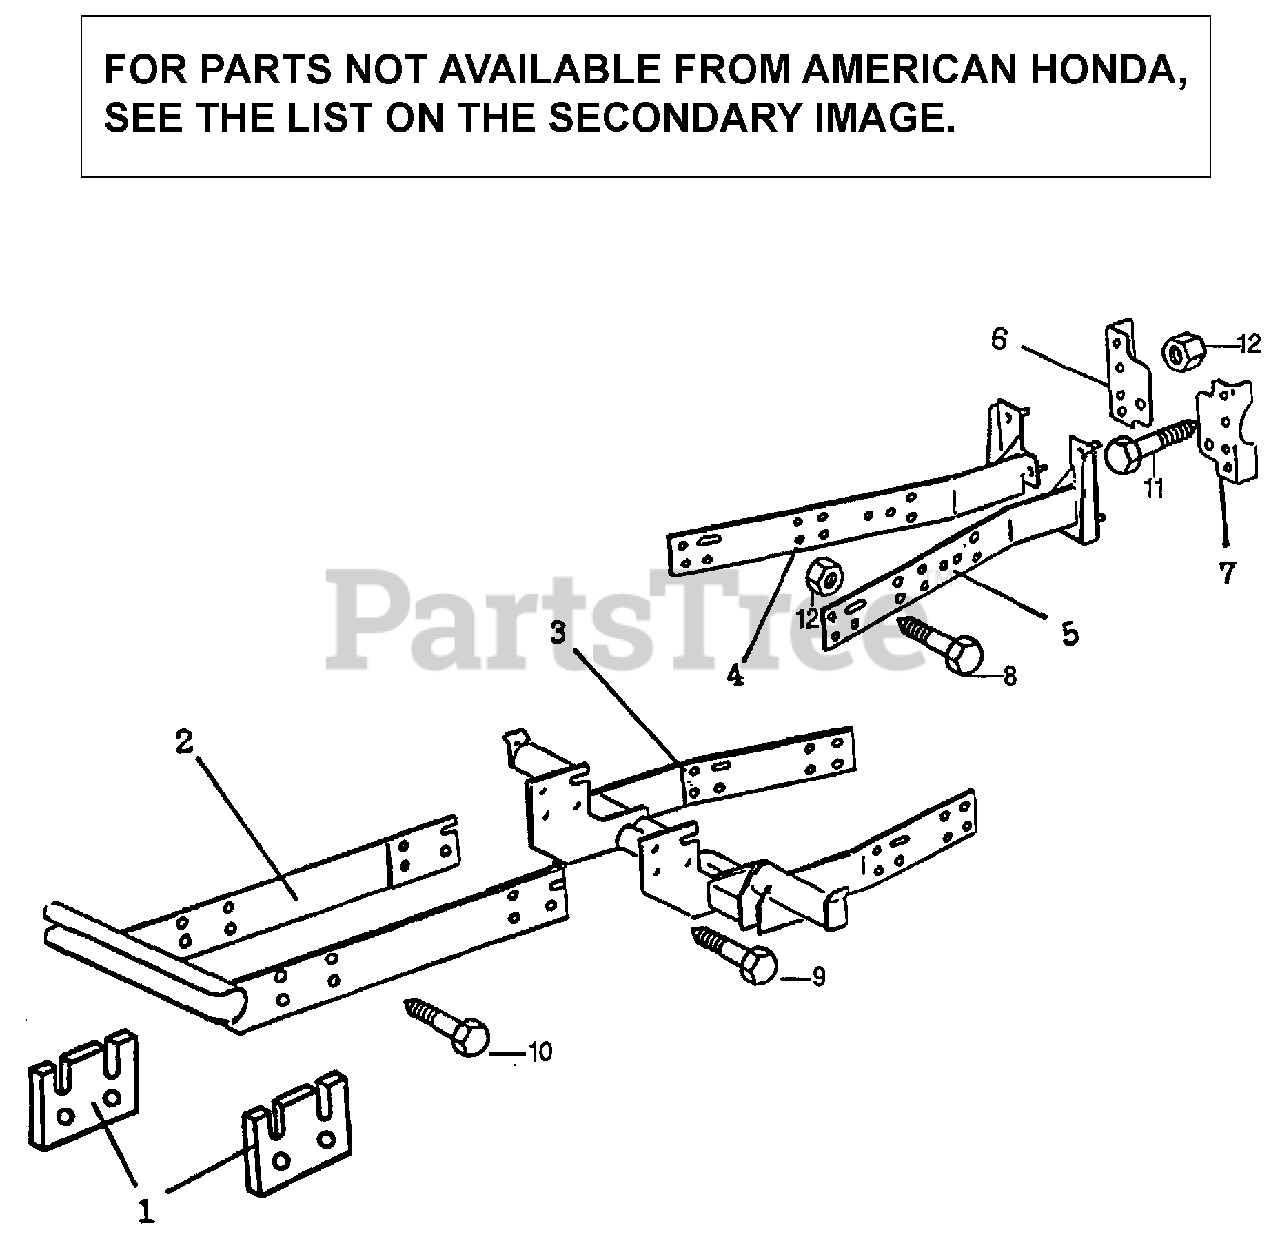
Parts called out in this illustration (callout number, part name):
1	PLATE, SPACER
9	SCREW, HEX. CAP (12X1.25X55)
10	SCREW, HEX. CAP (12X1.25X50)
11	SCREW, HEX. CAP (12X1.25X30)
